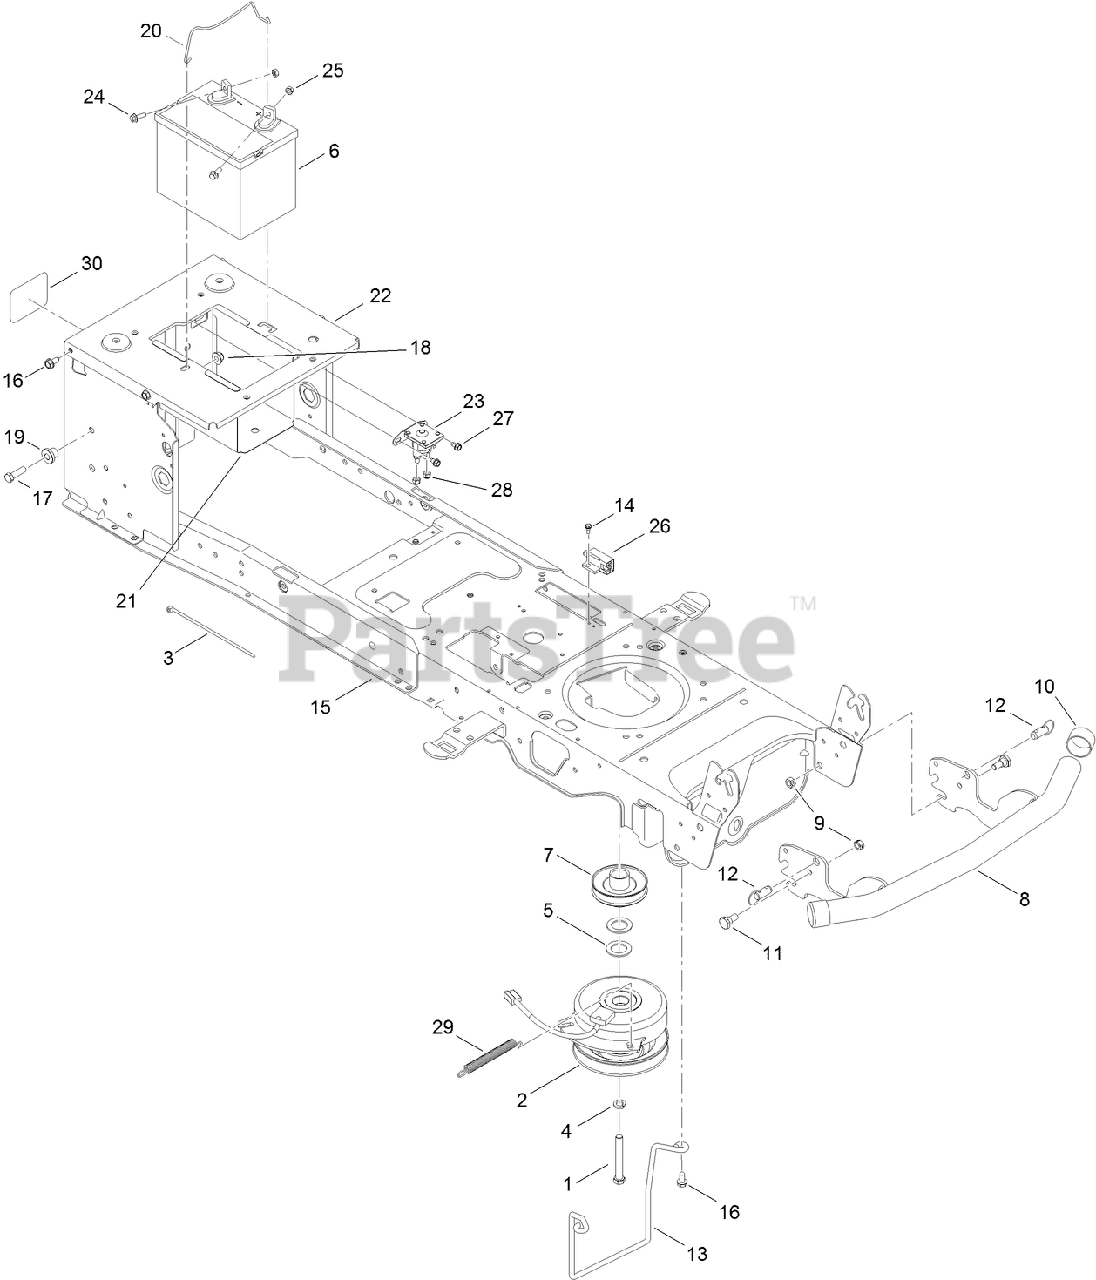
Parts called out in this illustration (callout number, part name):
1	SCREW-HH
2	CLUTCH-PTO, ELECTRIC
3	TIE-CABLE
4	WASHER-LOCK
5	WASHER-FLAT
6	BATTERY-245, CCA,DRY (FLAT TOP)
7	PULLEY-ENGINE
8	BUMPER-UNIVERSAL
9	NUT-LOCK
10	CAP-HUB
11	BOLT-SHOULDER
12	PIN-RELEASE, QUICK
13	ROD-KEEPER
14	BOLT-SHOULDER
15	LOWER FRAME ASM
16	SCREW-TAP
17	SCREW-HH
18	NUT-LOCK, FLANGE
19	SPACER-SHOULDER
20	ROD-HOLDDOWN, BATTERY
21	TRAY-BATTERY
22	BRACKET-FRAME, SEAT
23	SOLENOID-12V, 2 POST 2 TAB
25	NUT-SEMS
26	SWITCH-INTERLOCK, NO/NC
27	SCREW-TAP
28	NUT-LOCK, FLANGE
29	SPRING-EXTENSION
30	DECAL-RELEASE
